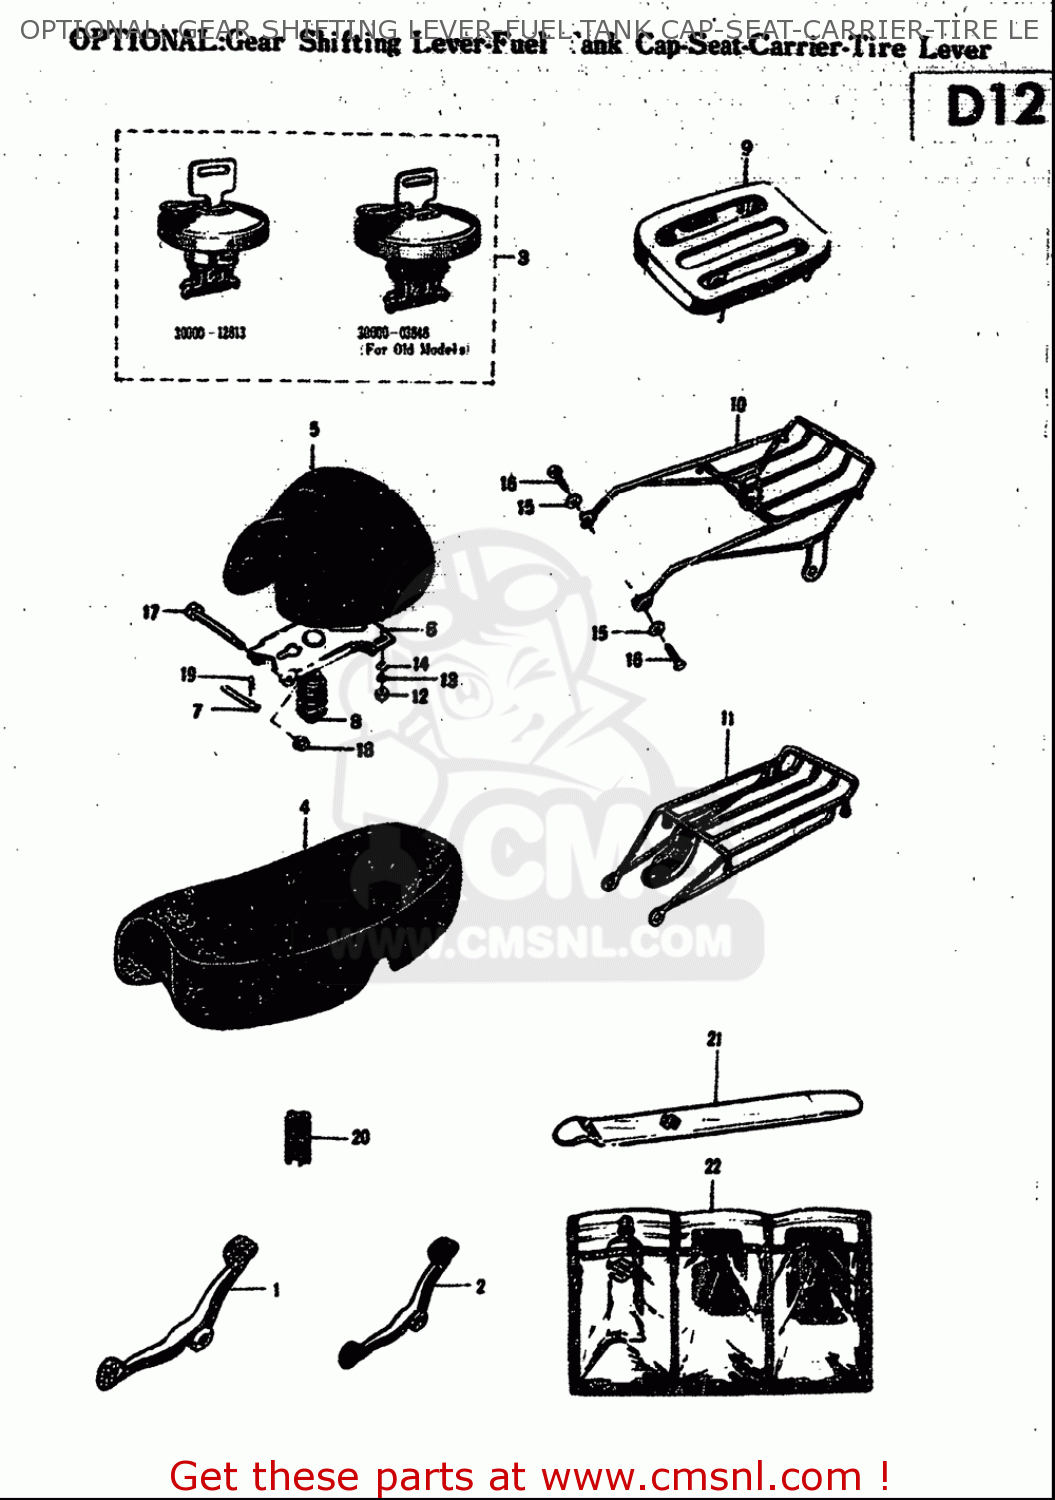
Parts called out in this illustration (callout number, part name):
12	NUT
13	WASHER,LOCK
14	WASHER
15	WASHER
18	NUT
19	CLIP
20	CLIP
